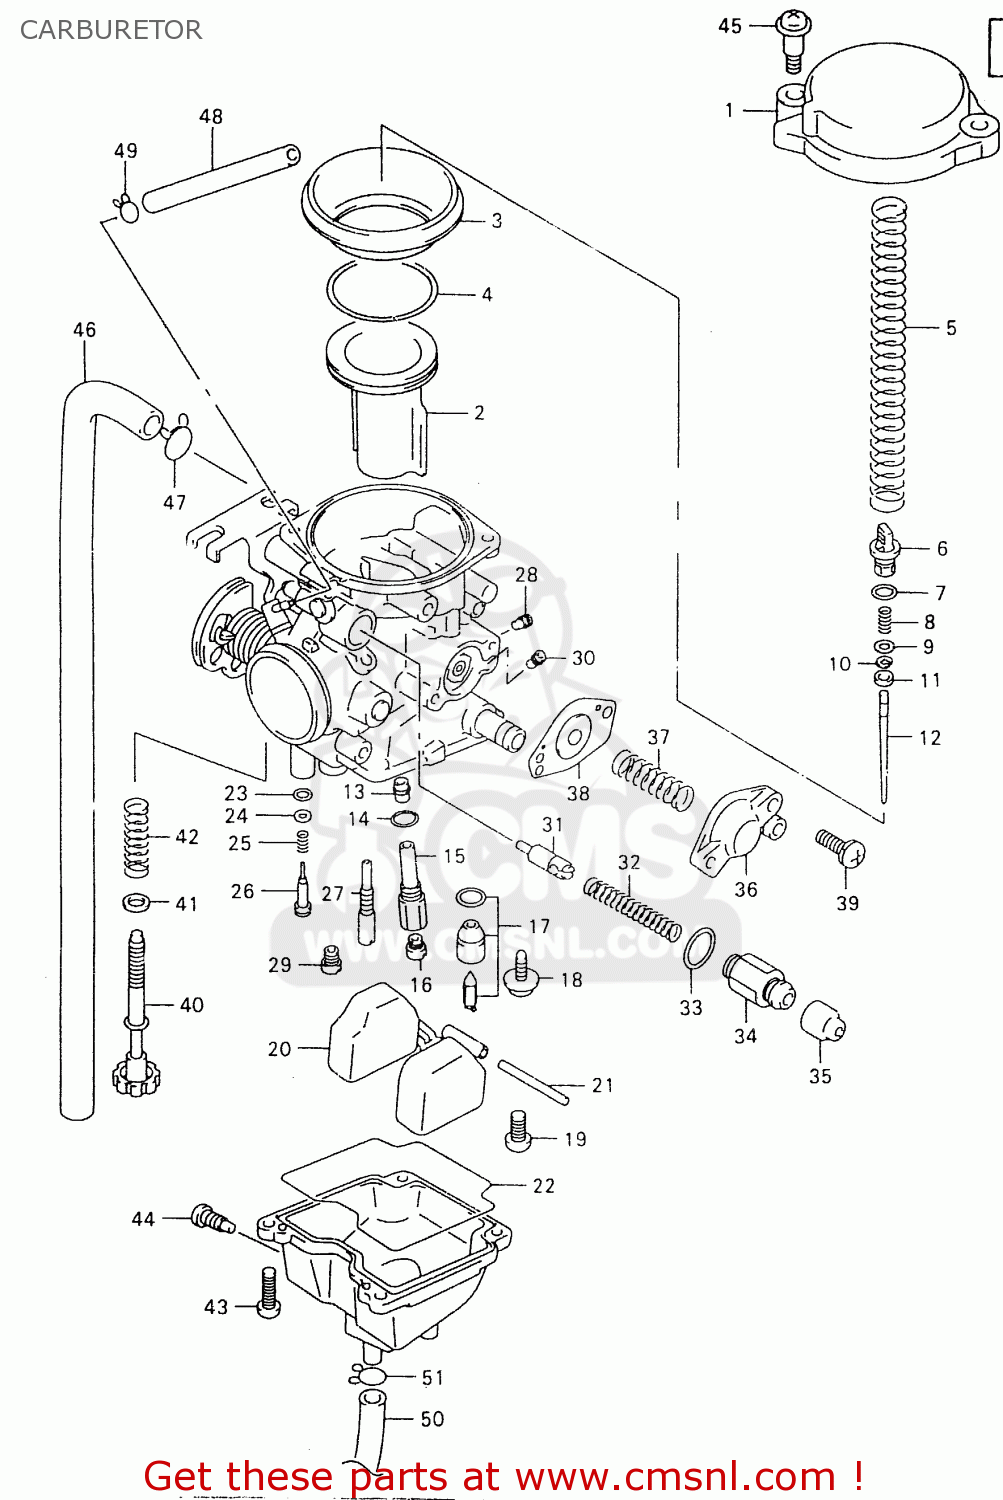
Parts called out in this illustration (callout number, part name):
1	COVER,DIAPHRAGM
2	VALVE,PISTON
3	DIAPHRAGM
4	RING
5	SPRING
6	HOLDER
7	O RING(D:1.9,ID:4.8)
8	SPRING
9	WASHER
10	E RING,MULTIPLE JET NOZZLE
11	RING
12	NEEDLE,JET
13	JET,NEEDLE(P-0)
14	O RING
15	HOLDER,JET
16	JET,MAIN(115)
17	VALVE ASSY,NEEDLE
18	SCREW
19	SCREW
20	FLOAT ASSY
21	PIN,FLOAT
22	GASKET (NAS)
23	O RING,PILOT AIR SCREW
24	WASHER
25	SPRING,THROTTLE SCREW
26	ADJUSTER
27	JET,PILOT(17.5)
28	JET,MAIN(87.5)
29	JET,MAIN(52.5)
30	JET,PILOT AIR(140)
31	PLUNGER
32	SPRING
33	O RING
34	HOLDER,GUIDE
35	CAP
36	COVER ASSY
37	SPRING
38	DIAPHRAGM ASSY
39	SCREW
40	SCREW,ADJUST
41	PACKING (NAS)
42	SPRING
43	SCREW
44	SCREW,DRAIN
45	SCREW
46	HOSE
47	CLIP
48	HOSE
49	CLIP
50	HOSE
51	CLIP
